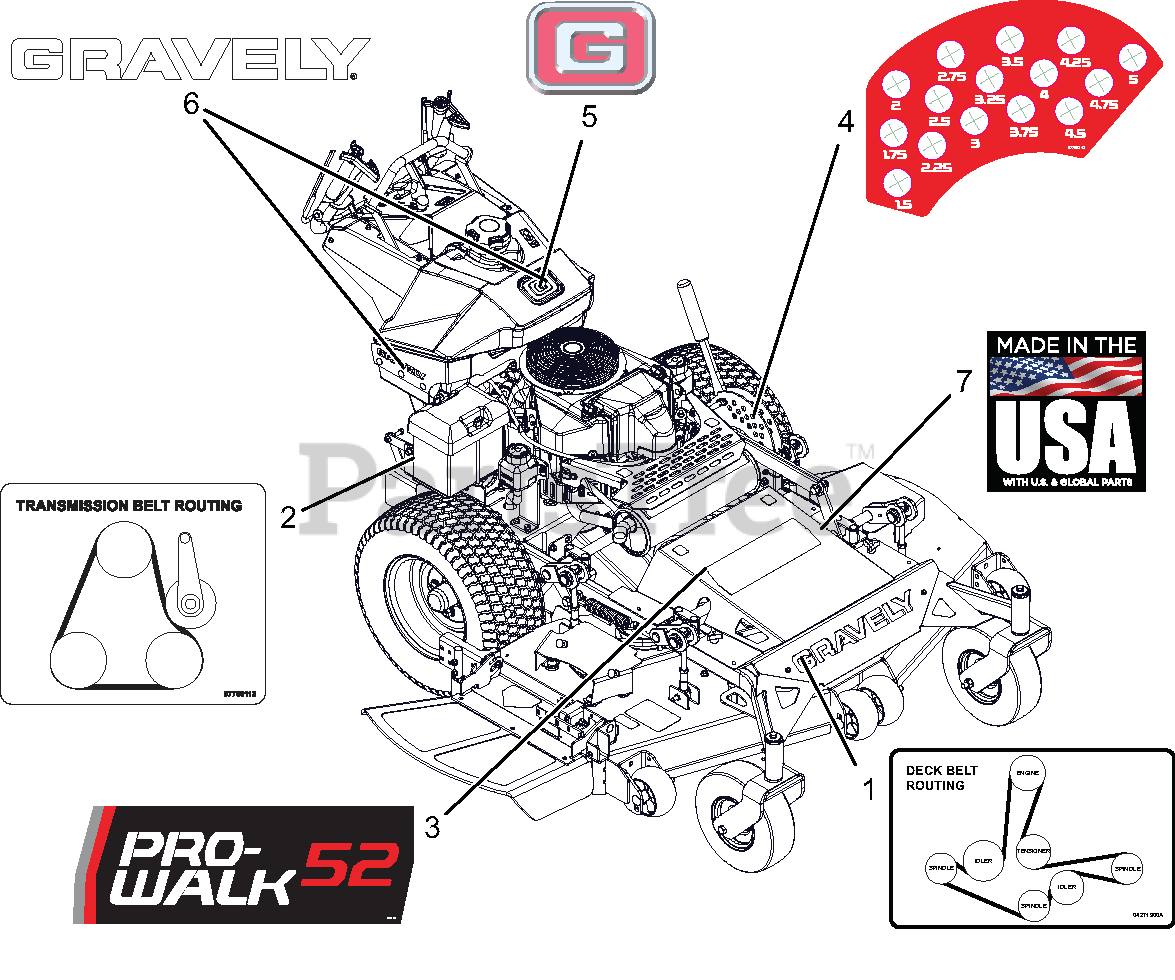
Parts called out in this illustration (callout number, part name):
1	DECAL, BELT ROUTING
2	DECAL, HYDRO BELT 36 PROSTANCE
3	DECAL, PRO WALK 52"
4	DECAL, HOC
5	DECAL, GRAVELY BRAND
6	DECAL, 6.5" GRAVELY LOGO
7	DECAL, MADE IN USA
